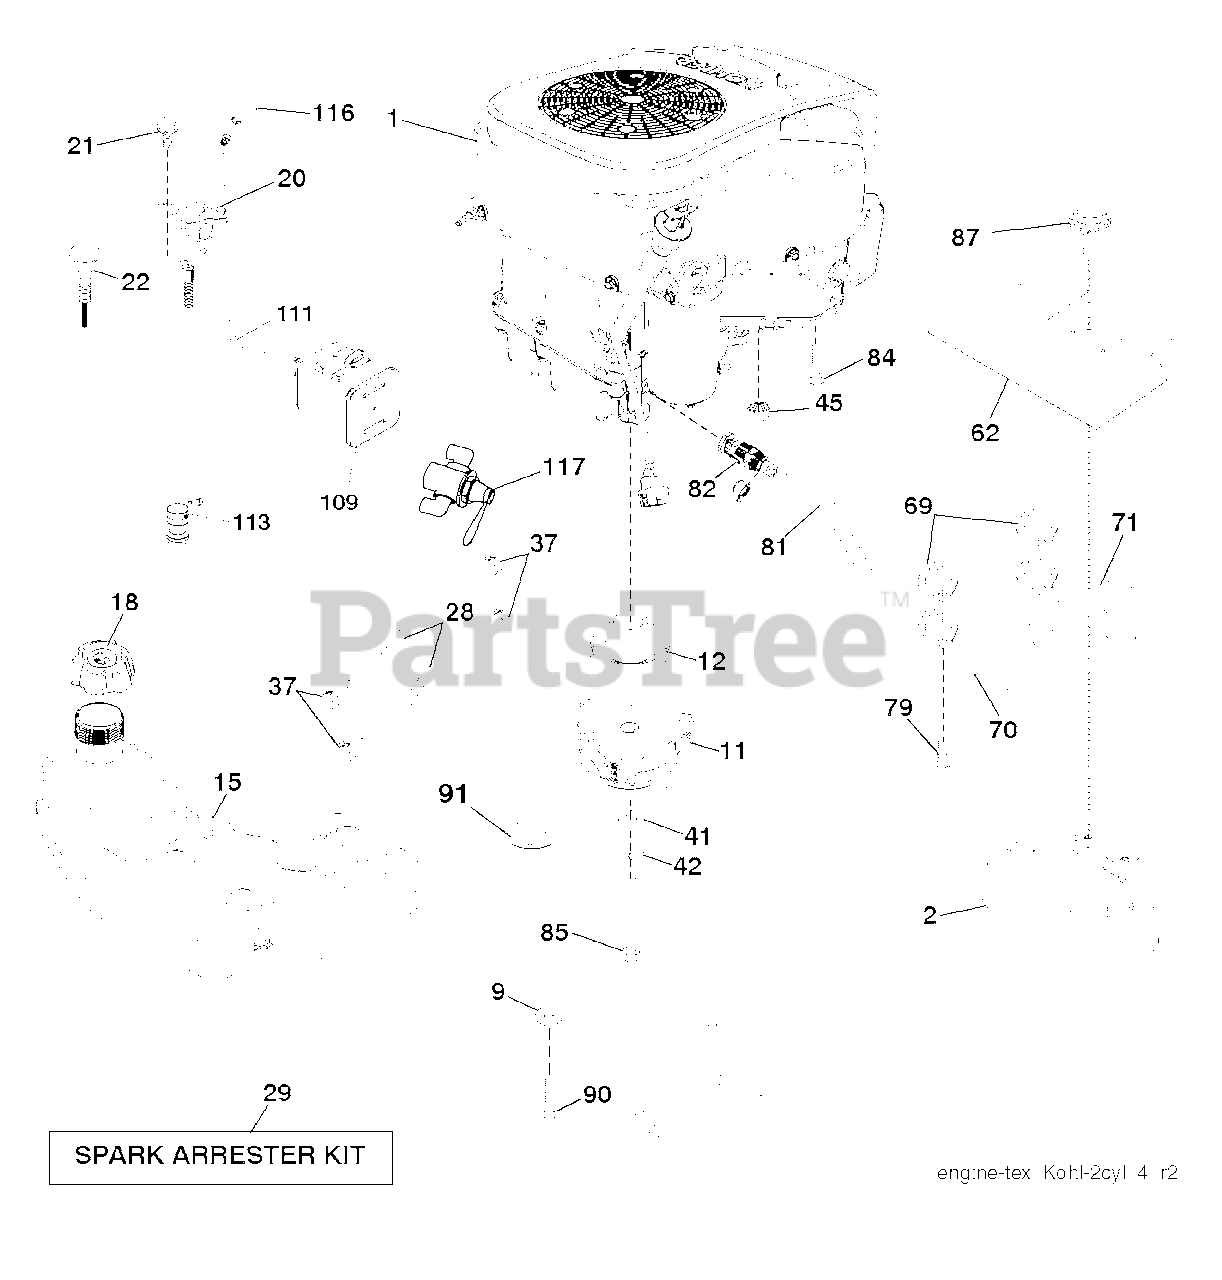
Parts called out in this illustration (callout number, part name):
2	MUFFLER.ASM.TWN.EXTNDED.DFLCTR
9	KEEPER BELT ENGINE
11	CLUTCH.OGURA.5.0PD.GT1.5A-EH07
12	PULLEY.ENGINE.TUFFTORQ
15	TANK.ASM.4.GAL.CARB.2.PORT.REA
18	CAP ASSY FUEL 3" GRAY
20	CONTROL.THROTTLE.PRO.KOHLER
21	SCREW.#10 X 0.750.BOS
22	CONTROL.CHOKE.ERGO.PUSH-IN.BLA
28	LINE.FUEL.64"REAR.EMIS
29	KIT.SPARK ARRESTOR 794945 B&S
37	HOSE CLAMP
42	LOCKWASHER
45	NUT
62	SHIELD.HEAT.MUFFLER
69	GASKET.EXHAUST.KOHL.CV18-CV26
70	PIPE.EXHAUST.LH.CV18/20
71	PIPE.EXHAUST.RH.CV18/20
79	SCREW.SOCKET HD.5/16-1
81	TUBE, DRAIN OIL ASM.
82	VALUE.OIL.DRAIN
84	SCREW 3/8-16X1
85	BOLT HEX 7/16-20 X 3.75 GR. 5
87	Bolt, 5/16-18 X 1-3/4
90	SCREW 3/8-16X1
91	BUSHING.1.375OD
109	CANNISTER, CARBON
111	RP PURGE LINE
113	VALVE.SLANT.CARTRDG.90 DEG.TEX
116	KNOB - SHIFT
117	VALVE FUEL RESERVE
